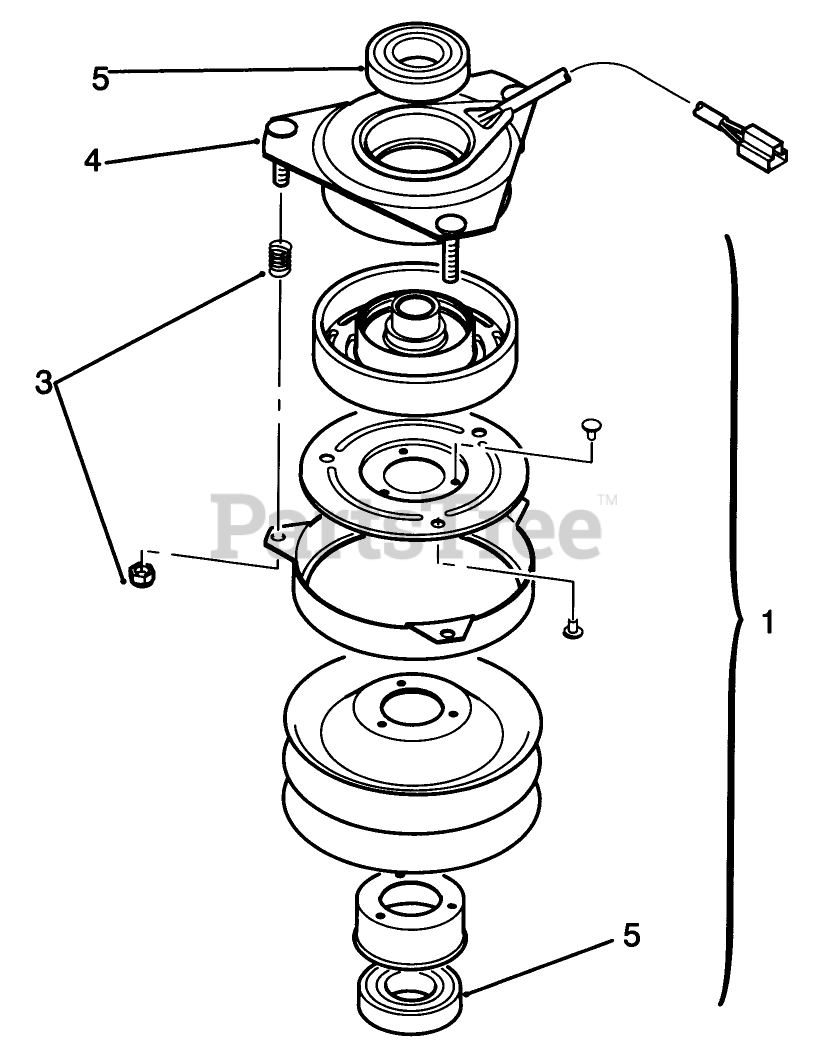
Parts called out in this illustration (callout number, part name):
1	ROTOR & ARMATURE ASSY
3	ACCESSORY PKG SRVC PART
4	FIELD ASSY (SRVC PART)
5	BEARING-ELEC CLUTCH
